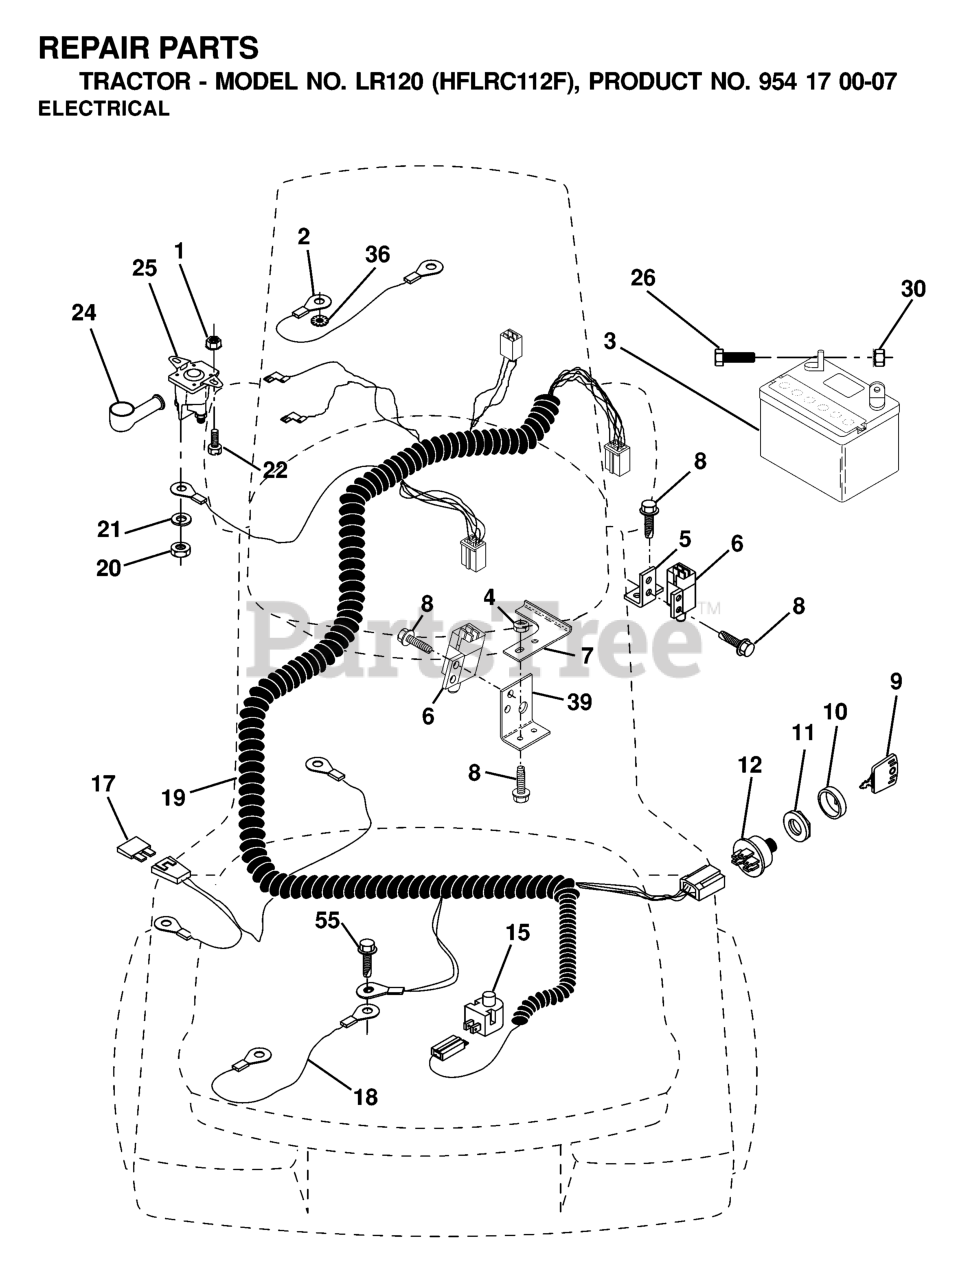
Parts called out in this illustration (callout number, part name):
1	Nut, Keps Blk Hex 1/4-20 UNC
2	CABLE.BATTERY.6GA.16"RED
3	REPL BY 532 12 38-99
5	BRACKET LT
6	SWITCH INTERLOCKT
7	KEEPER, ACTUAT. L.R.
9	KEY MLD GEN DELTA
10	COVER SWITCH KEY
11	NUT, IGNITION
12	IGNITION SWITCH
15	RP.SWITCH.PLUNGER.NC.GRAY
17	FUSE 15 AMP
18	CABLE ASSY
19	HARNESS IGN. HEADLIGHT
20	NUT
21	LOCKWASHER
22	BOLT
24	TERMINAL COVER
25	SOLINOID
26	BOLT.HEX.1/4.X.3/4.DICHROMATE
30	NUT
36	Washer, Lock, Internal Tooth 1/4
55	Screw 5/16-18 x 1/2 Hex, Self Tapping 5/16-18 x 1/2
